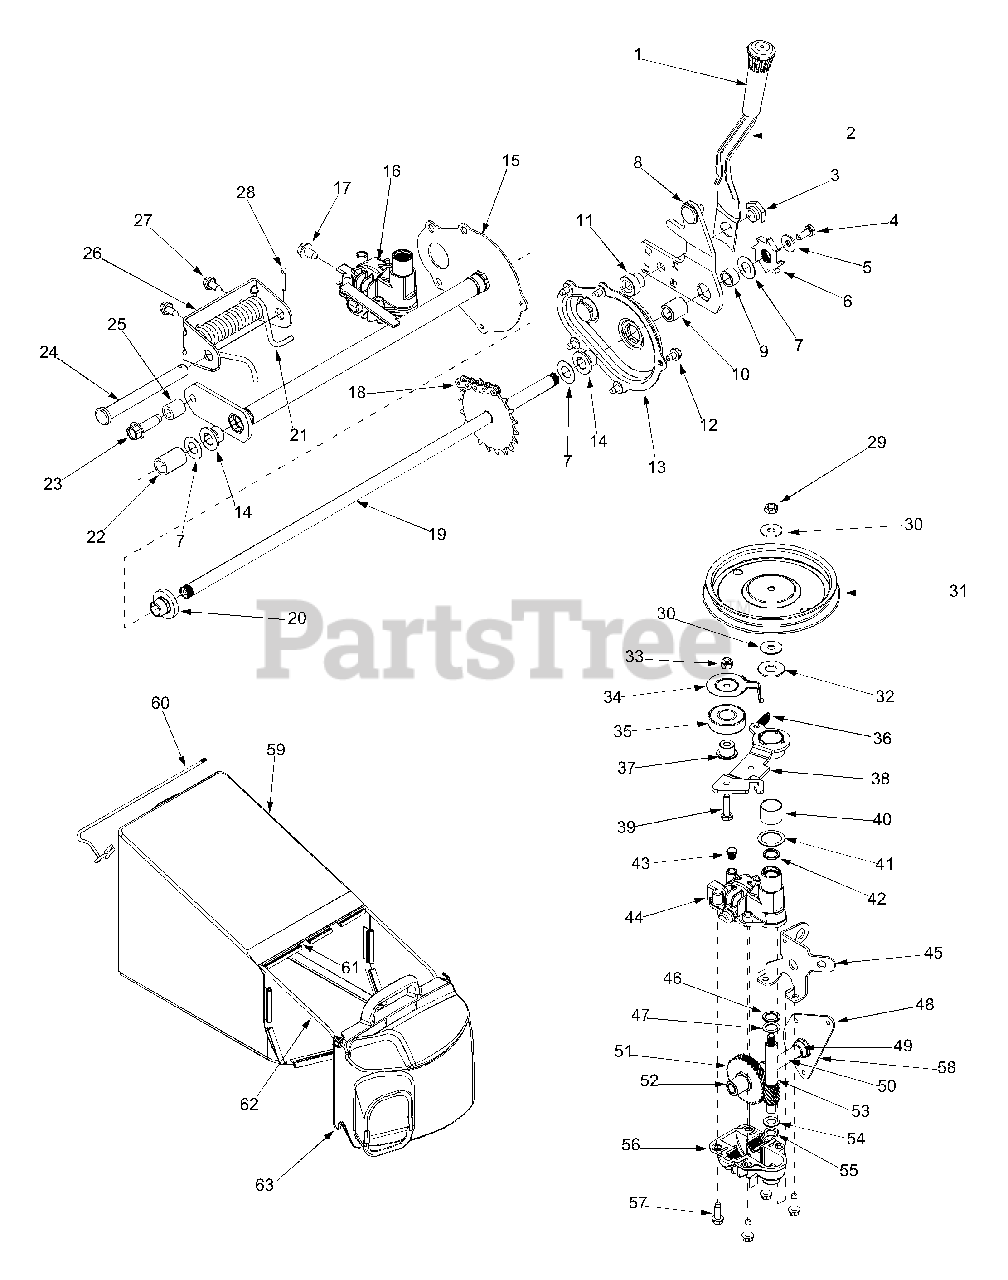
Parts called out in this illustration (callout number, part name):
2	Spring Lever
3	Shoulder Nut.825 x.165 Lg.
4	Cap Screw 1/4-20 x.620
5	Bell Washer.285 ID x.75 OD
6	Wheel Rachet
7	Flat Washer.508 ID x 1.0 OD
9	Spacer.510 ID x.70 OD
10	Sleeve Bearing.504 ID x.830 OD
11	Shoulder
12	Tap Screw 1/4-20 x.375
16	Transmission Assembly Complete
17	Hex Screw 5/16-18
18	Chain
19	Rear Axle Assembly
20	Flange Bearing.506 ID x.715 Lg
21	Torsion Spring
22	Spacer.550 ID x.750 OD
23	Screw 3/8-16 x.25
24	Clevis Pin.50 Dia x 4.82 Lg.
25	Spacer.385 ID x.624 OD
28	Cotter Pin
29	Hex Jam Nut 5/16-24
30	Bell Washer.325 ID x.930 OD
31	Pulley
32	Flat Washer.510 ID x 1.120 OD
33	Hex Jam Nut 1/4-28
34	Belt Keeper
35	Bearing
36	Extension Spring
37	Flange Spacer
38	Idler Bracket Assembly
39	Hex Cap Screw 1/4-28 x 1.0
40	Bearing Sleeve
41	Flat Washer.885 ID x 1.45 OD
42	Oil Seal
44	Upper Housing Assembly
47	Thrust Washer.504 ID x.70 OD
48	Pivot Bracket
49	Flange Bearing
50	Output Shaft 6T
51	Gear 34T
52	Bearing
53	Pinion Shaft 10T
54	Thrust Washer 3/8 x.70
55	Thrust Washer.388 x.625
56	Lower Housing Assembly
57	Hex Screw 1/2-20 x.75
58	Shaft Assembly
59	Grassbag - Yellow
61	Pivot Rod
63	Grassbag Cover
